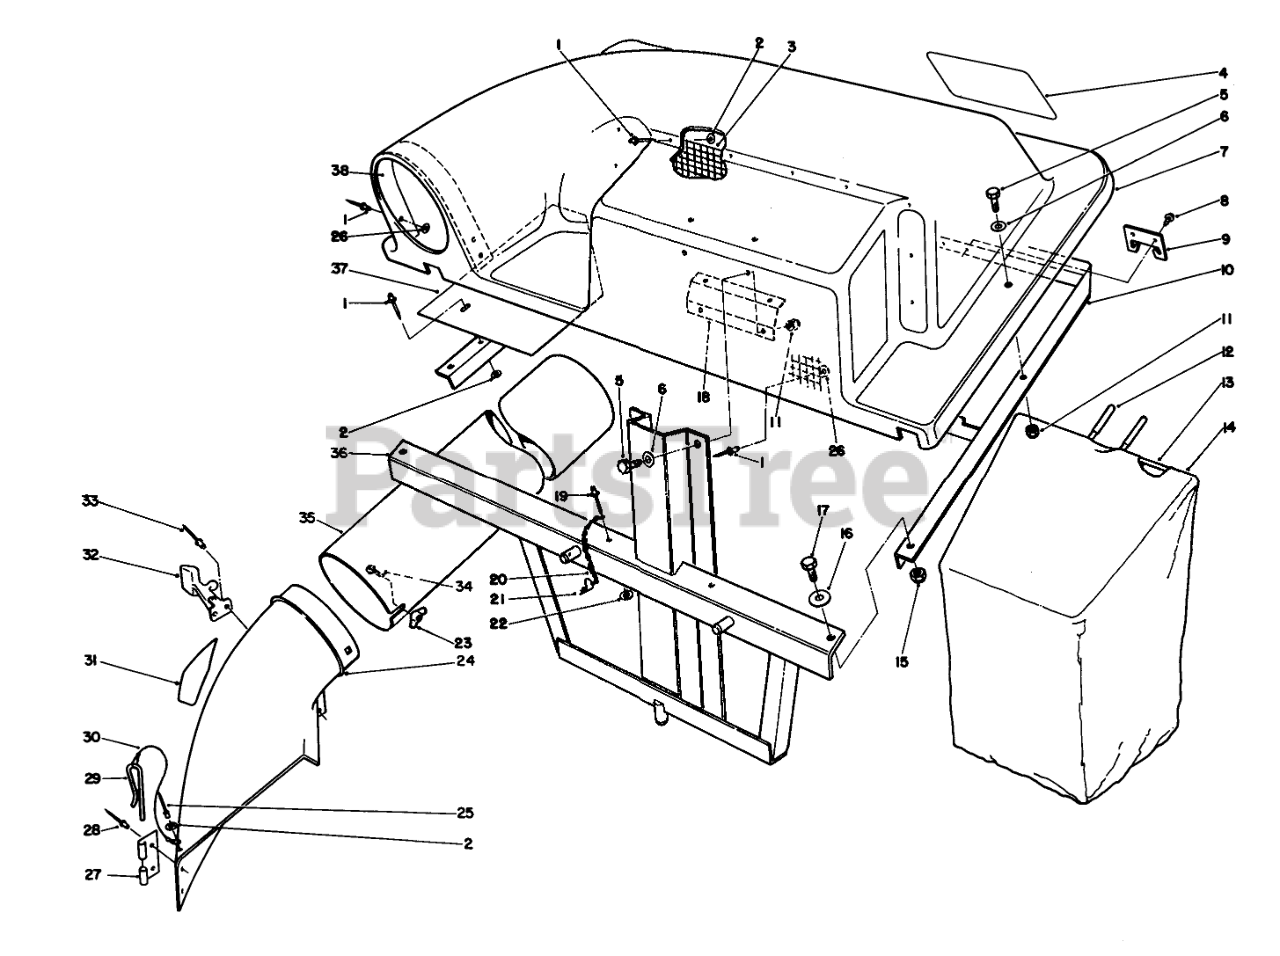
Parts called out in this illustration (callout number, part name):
1	RIVET-POP
2	WASHER-PLAIN
3	SCREEN
4	DECAL-BAGGER, TWIN
5	SCREW-HH
6	WASHER-PLAIN
7	COVER-BAGGER, TWIN
8	SCREW-HWH
9	BRACKET-FRAME, BAG
10	Cover-Frame
11	NUT-LOCK, NI
12	GRIP-HANDLE, BAG
13	Frame-Bag
15	NUT-LOCK, NI
16	WASHER-FLAT
17	SCREW-HH
18	Plate-Backup
20	10 LINK CHAIN W/O HOOK
21	PIN-HAIR
22	WASHER-BACK
23	NUT-WING SPECL
24	Chute Assembly (Incl. Ref. #2, 25 & 27-33)
25	RIVET-BLIND
26	WASHER-FLAT
27	BRACKET-MOUNTING, CHUTE
28	RIVET-BLIND
29	PIN-LOCKING, CHUTE
30	LANYARD
31	DECAL-DANGER
32	Latch-38"
33	RIVET-POP
34	BOLT-CARR
35	TUBE(ROUND&LONG)
36	Frame-Mounting
37	Baffle
38	Support Inlet
